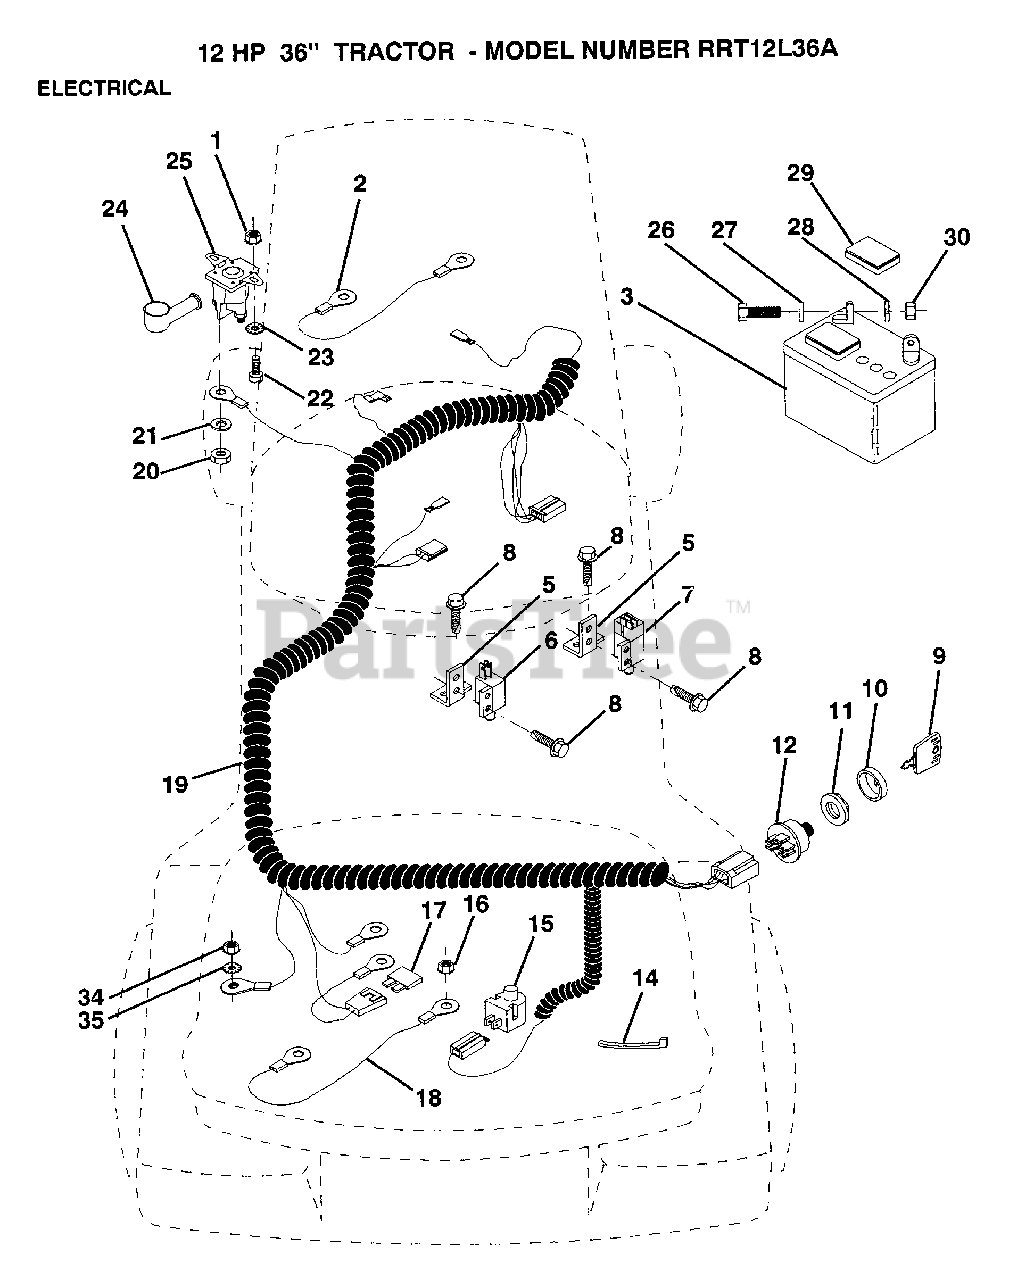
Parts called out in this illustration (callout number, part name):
1	NUT
5	BRACKET LT
6	SWITCH-INTER. GT
7	SWITCH INTERLOCKT
8	SCREW
9	KEY
11	NUT IGNITION
14	WIRE TIE
15	SWITCH SEAT
17	FUSE HYT
18	CABLE ASSY
19	"HARNESS,IGNITION"
20	NUT
22	BOLT
26	BOLT LT
27	WASHER
28	LOCKWASHER
29	"CAP,BATTERY "
34	NUT
35	LOCKWASHER
